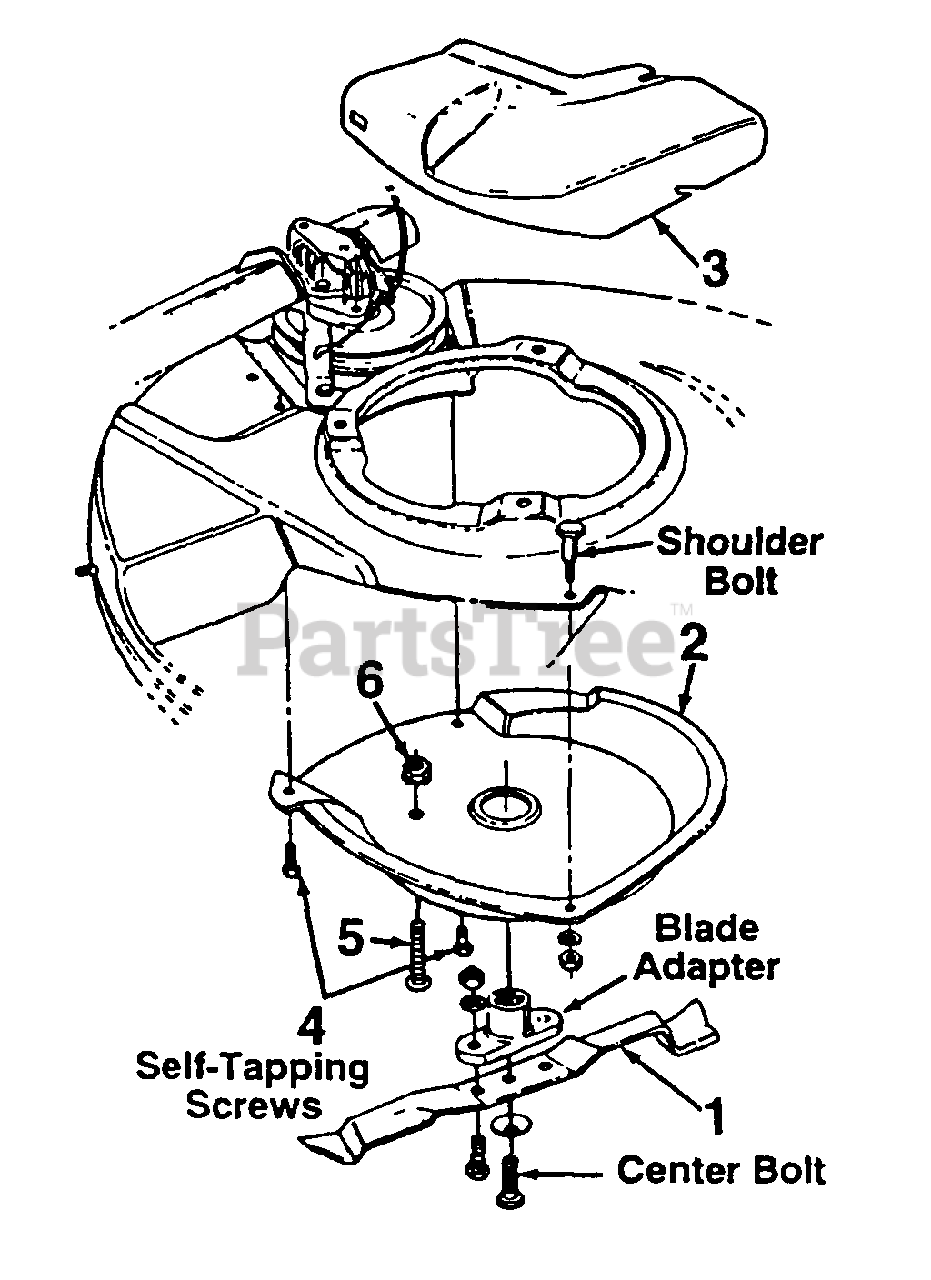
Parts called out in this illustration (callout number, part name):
1	Mulching Blade
4	Self-Tapping Screw
5	Phillips Scr. 1/4-20 x 1.5" Lg.
6	Hex Sems Nut 1/4-20 Thd.
